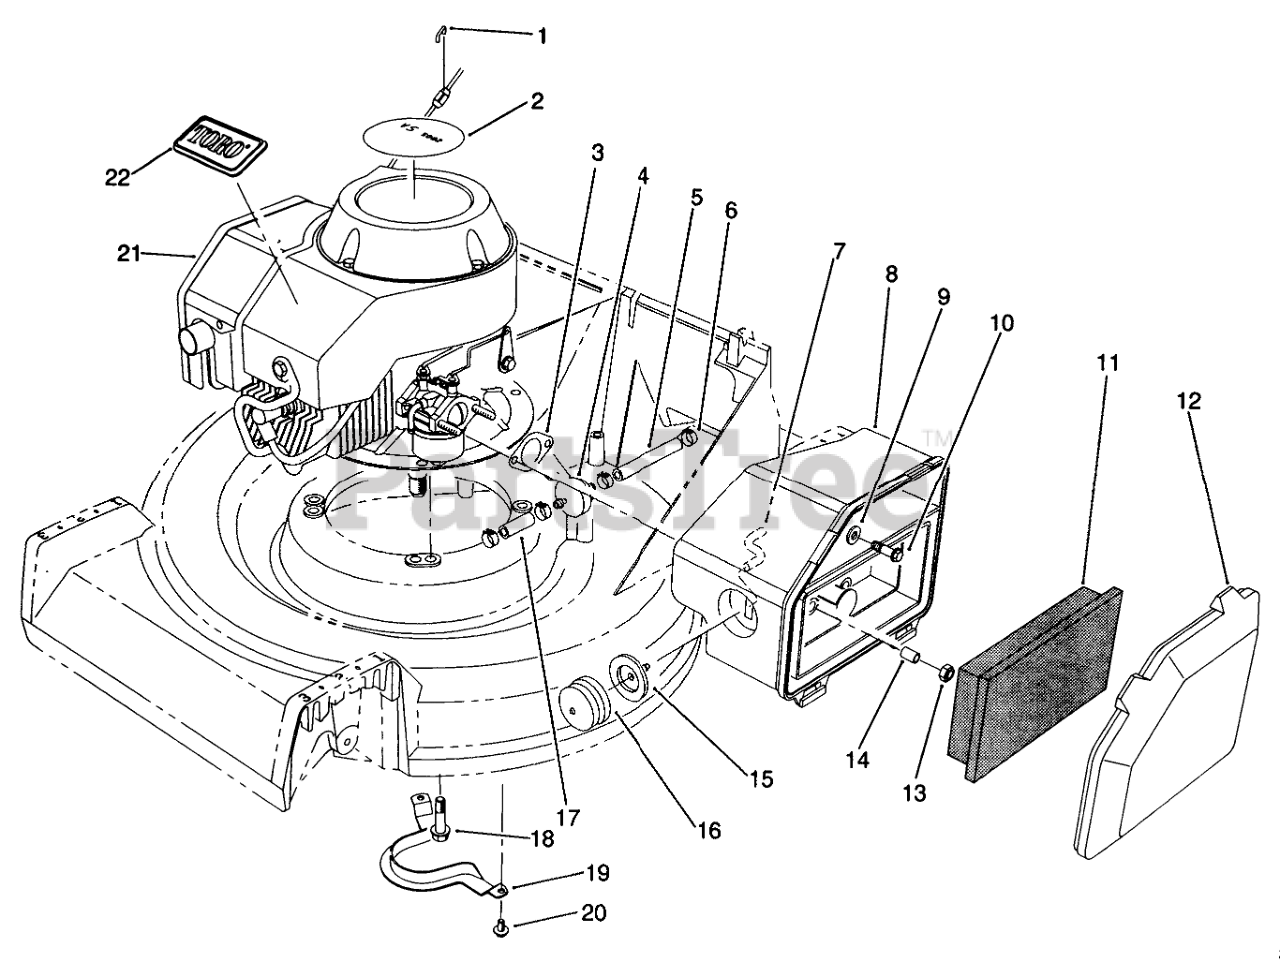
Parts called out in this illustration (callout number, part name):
1	SCREW-HH
2	WASHER-PLAIN
3	HAIRPIN COTTER
4	CONTROL ROD LINK
5	NUT-KEPS
6	CONTROL ROD SLEEVE
7	Engine
8	Nut
9	Decal Toro
10	Pedestal
11	BUSHING
12	NUT-HEX
13	PIN-COTTER
14	BELL CRANK WA
15	WASHER-FLAT
16	IDLER PULLEY R
17	Idler Arm (Incl. Ref. #11)
18	FITTING-GREASE
19	NUT-HEX
20	WHEEL COVER
22	Wheel & Tire Assembly, Rear (Incl. Ref. #21 & 23)
23	BEARING-BALL
24	FELT WASHER
25	WASHER-FLAT
26	WHEEL BOLT REAR
27	3/8-16 X 2-3/4 CAPSCR
